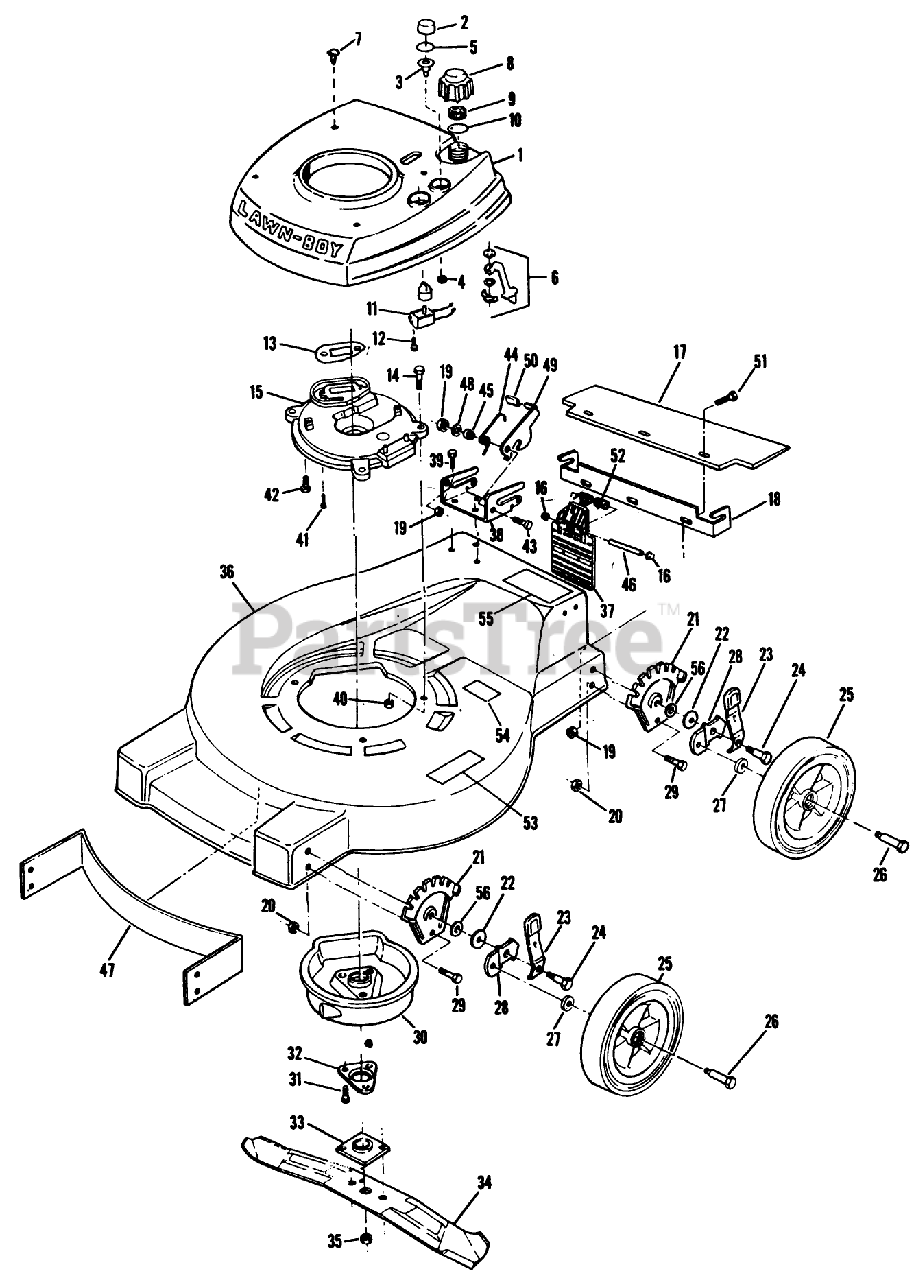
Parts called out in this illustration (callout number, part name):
4	LOCKNUT S
5	FILTER S
7	SCREW S
9	BAFFLE - FOAM SM
10	GASKET S
11	SWITCH
14	SCREW
15	PLATE,MUFFLER F
17	SHIELD
19	LOCKNUT E
20	LOCKNUT
22	WASHER
23	KNOB & SPRING
27	WASHER WROUGHT
31	SCREW
32	SUPPORT F
33	PLATE AND COLLAR ASM
35	NUT-BLADE
40	NUT-LOCK F
41	SCREW V
44	SPRING
46	ROD ROCK/HDWE
52	SPRING ASOC
53	PAD FOOT
54	Decal
55	Decal
56	WASHER WROUGHT
